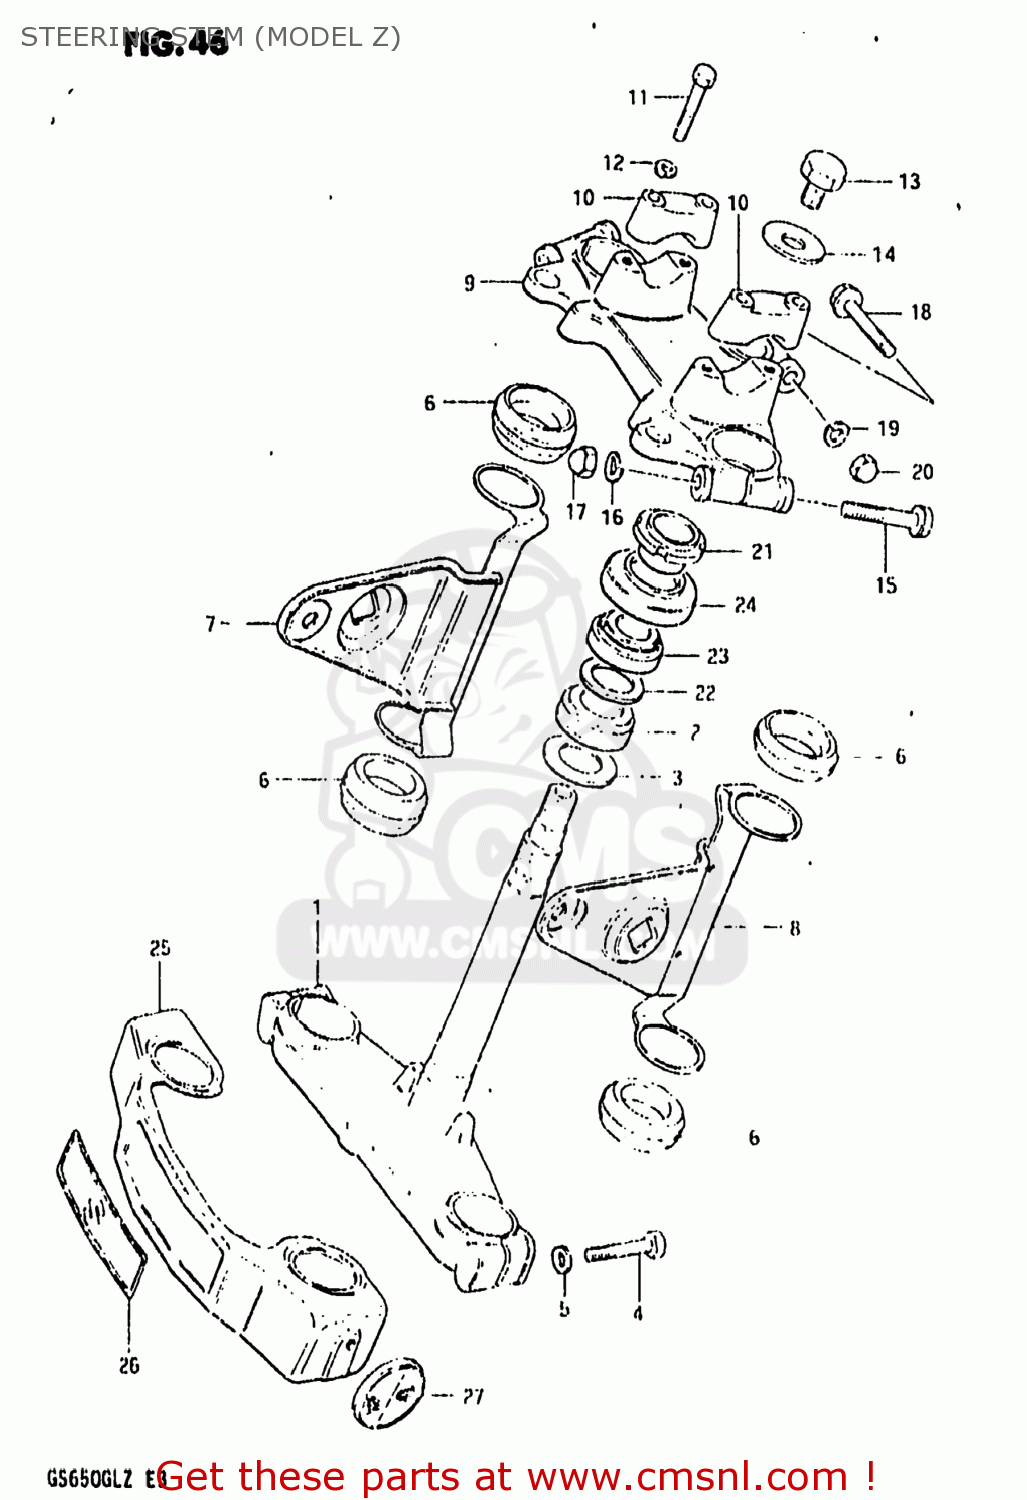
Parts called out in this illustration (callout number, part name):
1	STEM,STEERING
2	BEARING
3	WASHER,THRUST
4	BOLT 8X45
5	WASHER,LOCK,8.
6	CUSHION,HEADLAMP BRACKET
7	BRACKET,HEADLAMP,RIGHT
8	BRACKET,HEADLAMP,LEFT
9	HEAD,STEERING STEM
10	HOLDER,HANDLE UPR
11	BOLT
12	LOCK WASHER
13	BOLT(12X20)
14	WASHER
15	BOLT 10X55
16	LOCK WASHER
17	NUT
18	BOLT
19	LOCK WASHER
20	NUT,M8X1.25X12
21	NUT,STEERING STEM
22	WASHER(18.5X24X1)
23	TAPER,ROLLER BEARING
24	DUST SEAL,STEERING,UPPER
25	COVER,FRONT FORK
26	EMBLEM,FR FORK COVER
27	REFLEX REFLECTOR,RR
